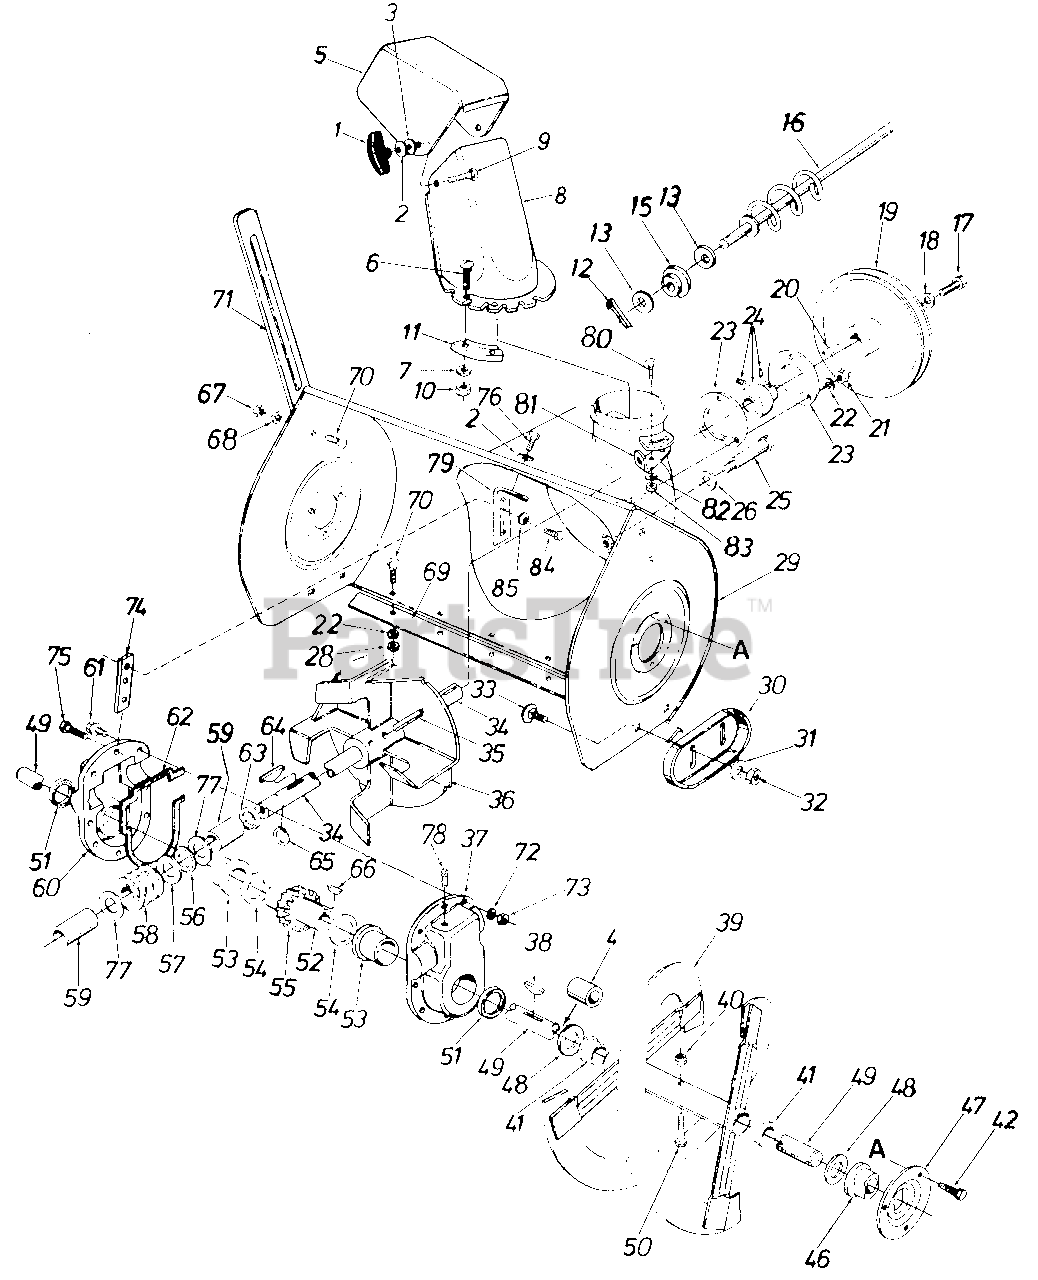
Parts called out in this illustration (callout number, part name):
1	Hand Knob Ass'y.
2	Bell-Wash. .345 I.D. x .88 O.D. x .060
3	Fl. Wash. .312 I.D. x 1.125 O.D. x .125
4	Spacer
5	Top Chute
6	Truss Mach. Scr. 1/4-20 x .75"
7	Fl-Wash. 1/4" l.D.
8	Chute
9	Carr. Bolt 5/16-18 x 1.00" Lg.
10	Hex Cent L-Nut 1/4-20 Thd.
11	Chute Flange Keeper
13	Fl-Wash. .385" I.D. x .62"
15	Bushing
16	Chute Crank Ass'y.
17	Hex L-Scr. 5/16-18 x .88" Lg.
18	Bell-Wash. .345 I.D. x .88
19	V-Pulley .875 I.D. x 10.12
20	#9 Hi-Pro Key 3/16 x 3/4" Dia.
21	Hex Nut 5/16-18 Thd.
22	L-Wash. 5/16" l.D.
23	Bearing Hsg.-Self Aligning Brg.
24	Self Aligning Brg. .875 I.D.
25	Stud 3/8-16 x 2.75" Lg.
26	Bell-Wash. .400 I.D. x .88 O.D. x .060
28	Hex Nut 5/16-18 Thd.
29	Blower Hsg. Ass'y.
30	Slide Shoe
31	Bell-Wash. .400 I.D. x .88 O.D. x .060
32	Hex Jam Nut 3/8-16 Thd.
33	Carr. Bolt 3/8-16 x .62" Lg.
35	Spring Pin Spiral 5/16" Dia. x 1.75" Lg.
38	#91 Woodruff Key 1/4" x 3/4" Dia.
41	Plastic Bushing
42	Hex Wash. Hd. Self-Tap Scr. 5/16-24 x .62" Lg.
46	Flange Brg. w/Flats 1.0" l.D.
47	Bearing Hsg.-Spiral Hsg.
48	Fl-Wash. 1.06 I.D. x 1.75" O.D. x .100
50	Hex Bolt 5/16-18 x 1.75" Lg.
51	Oil Seal 1.50" I.D.
52	Worm Gear Shaft
53	Flange Brg. 1.503 I.D.
54	Fl-Wash. 1.5 I.D. x 2.0 O.D.
55	Double Threaded Worm Gear
56	Thrust Brg. .88 I.D. x 1.44 O.D. x .078
57	Fl-Wash. .88 I.D. x 1.40 O.D.
58	Double Threaded Worm-L. H .
59	Sleeve Brg. .875 I.D.
60	Complete Gear Hsg. Half-R.H.
61	Hex Bolt 5/16-18 x 1.0" Lg.
62	Gasket
63	Oil Seal .875" I.D.
64	#9 Hi-Pro Key 3/16 x 3/4" Dia.
65	Snap Ring-.875" Dia.
66	#91 Woodruff Key 1/4 x 3/4" Dia.
67	Hex Nut 5/16-18 Thd.
68	L-Wash. 6/16" I.D.
70	Carr. Bolt 5/16-18 x .62" Lg.
71	Drift Cutter
72	Wave Wash. 5/16" I.D.
73	Hex Ins. L-Nut 5/16-18 Thd.
74	Gear Hsg. Support Plate
75	Hex Bolt 5/16-18 x 1.25"
76	Hex Wash. Hd. Self-Tap Scr. 5/16-18 x .75" Lg.
77	Fl-Wash. .88 I.D. x 1.40 O.D.
80	Carr. Bolt 5/16-18 x .75" Lg.
82	Bell-Wash. .345 I.D. x .88"
83	Hex Nut 5/16-18 Thd.
84	Hex Bolt 1/4-28 x .75" Lg.
85	Bell-Wash. .28" I.D. x .75" O.D.
